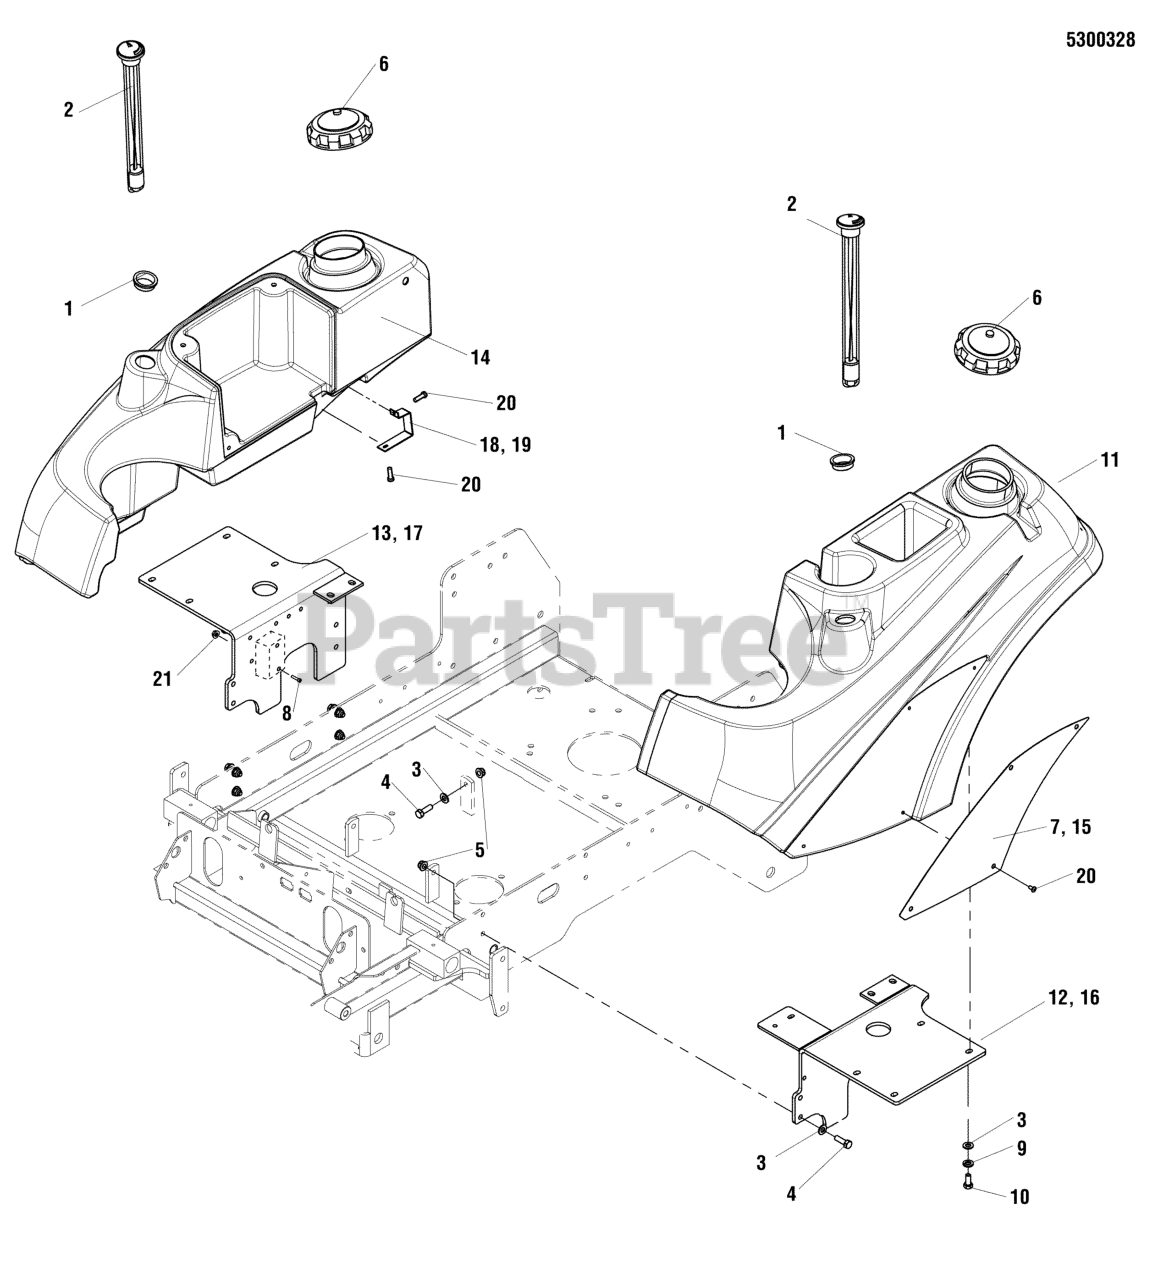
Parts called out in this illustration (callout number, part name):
1	GROMMET, FUEL GUAGE
2	GAUGE, FUEL, 12
3	WASHER, 5/16" SAE
4	BOLT, 5/16-18 X 1" GD5 YZ
5	NUT, 5/16-18 HEX NYLOCK FLANGE
6	CAP, FUEL TANK (DIESEL)
7	BADGE, IS2000 - IS3000 - RED MODEL
8	SCREW, #10-24 X 3/8" ALLEN BHBZ
9	WASHER, 5/16 LOCK CZ
10	BOLT, 5/16-18 X 3/4 GD5
11	TANK, FUEL, LH - DIESEL
12	WELD, TANK MOUNT - LH - BLK
13	WELD, TANK MOUNT - RH - BLK
14	TANK, FUEL, RH - DIESEL
15	BADGE, IS2000 - IS3000 - ORANGE MODEL
16	WELD, TANK MOUNT - LH - BLK
17	WELD, TANK MOUNT - RH - BLK
18	GUARD, FUEL TANK - RED MODEL
19	WELD, TANK MOUNT - ORANGE MODEL
20	SCREW, #10-24 X 3/8 ALLEN BHBZ
21	NUT, #10-24 HEX
